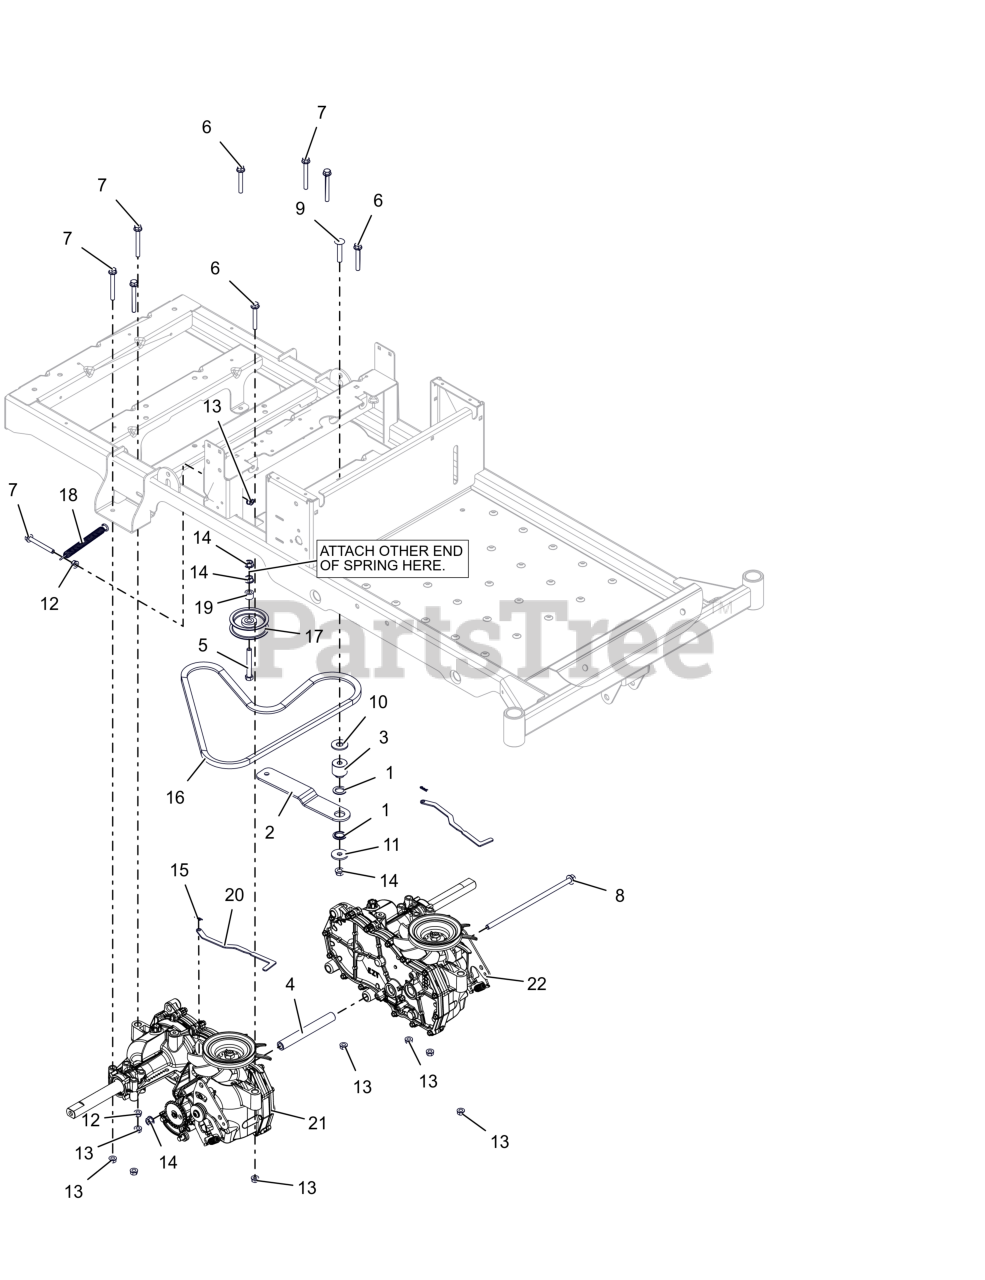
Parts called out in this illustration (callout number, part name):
1	BUSHING, IDLER ARM
2	IDLER ARM, GROUND DRIVE
3	SPACER, GROUND DRIVE IDLER
4	SPCR- TRANSAXLE .438X.75X6.125
5	BLT, HEX .38-16X2.75 G5 ZCC
6	BLT,HEX-FLG .31-18X2.25 G5 ZCC
7	BLT,HEX-FLG .31-18X2.75 G5 ZCC
8	BLT, HEX-FLG 0.375-16X9.75 GR5 ZC120
9	BLT,RHSSN.375-16X2.00 G5 ZCC
10	WSHR,FLT .563X1.375X.109 ZCC
11	WSHR,FLT .406X1.375X.135 ZCC
12	NUT,SPNLK-FLG .31-18 G5 ZCC
13	NUT,LK-CTR-FLG .31-18 GF ZCC
14	NUT-LK-CTR-FLG .375-16 GF ZCC
15	PIN-HAIR INT .06X.18X.77
16	V-BELT, HA-RAW EDGE
17	PULLEY, ENGINE CLUTCH 03608
18	SPRING, EXTENSION
19	BSHG-SLV .391X.688X.52 PM
20	BRKT, VALVE DUMP (BLACK)
21	TRANSAXLE, RH EZT-D-LONG SERV
22	TRANSAXLE, LH EZT-D-LONG SERV
